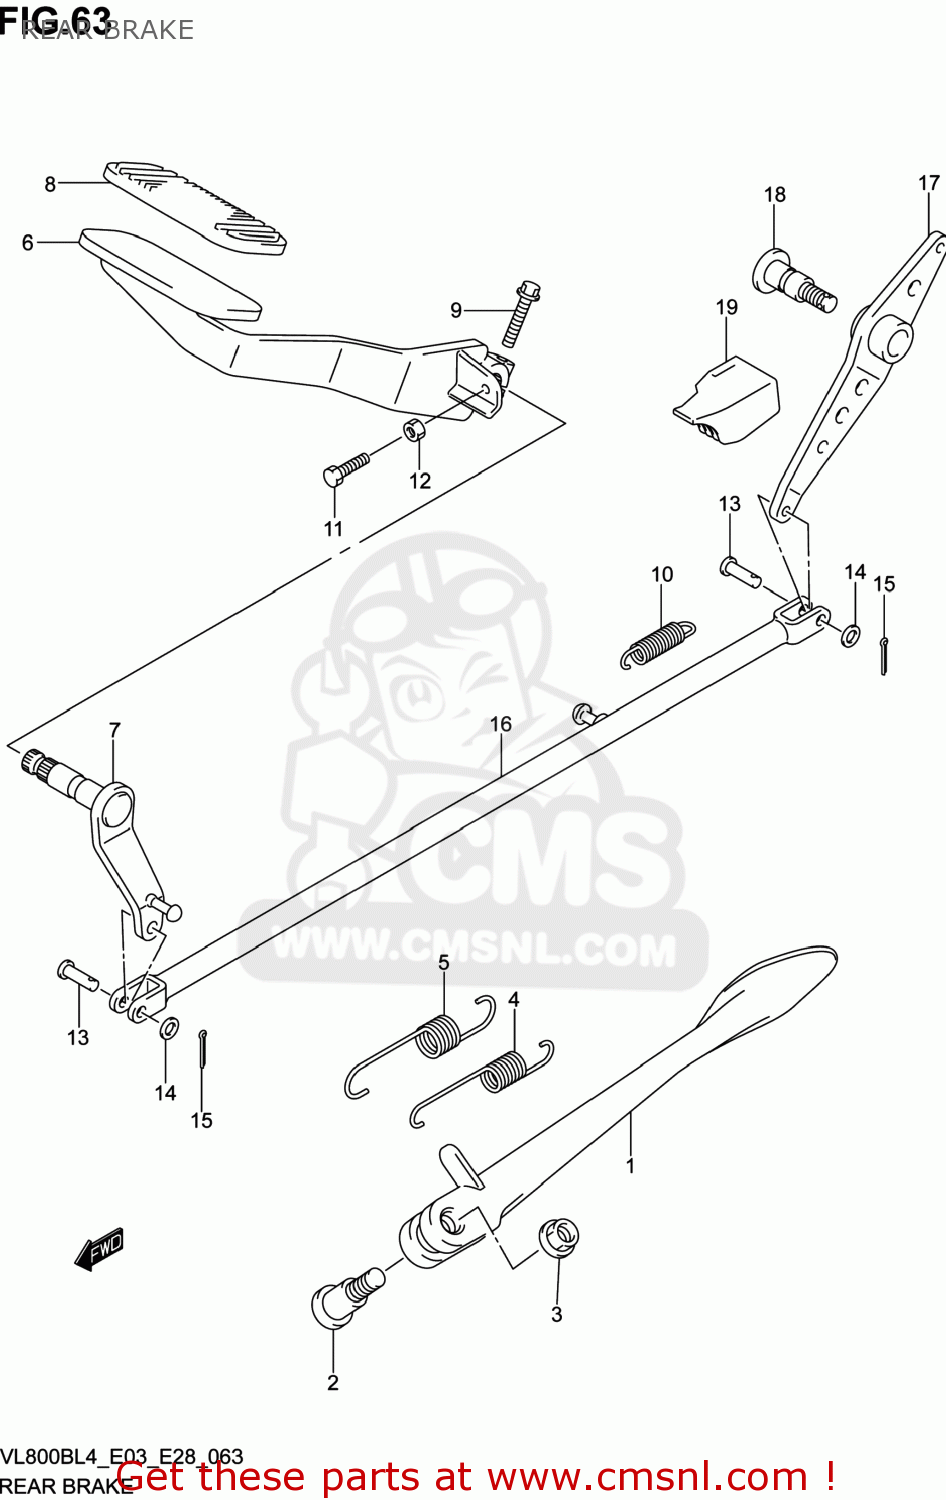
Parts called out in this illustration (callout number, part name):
1	STAND,PROP
2	BOLT(10X37.5)
3	NUT,PROP STAND
4	SPRING
5	SPRING
6	PEDAL,BRAKE
7	ARM,BRAKE ROD
8	RUBBER,BRAKE PEDAL
9	BOLT
10	SPRING
11	BOLT
12	NUT
13	PIN(6X18.2)
14	WASHER
15	PIN
16	ROD,RR BRAKE FR
17	LINK,RR BRAKE
18	SHAFT,BRAKE PEDAL
19	RUBBER,BRAKE LINK
